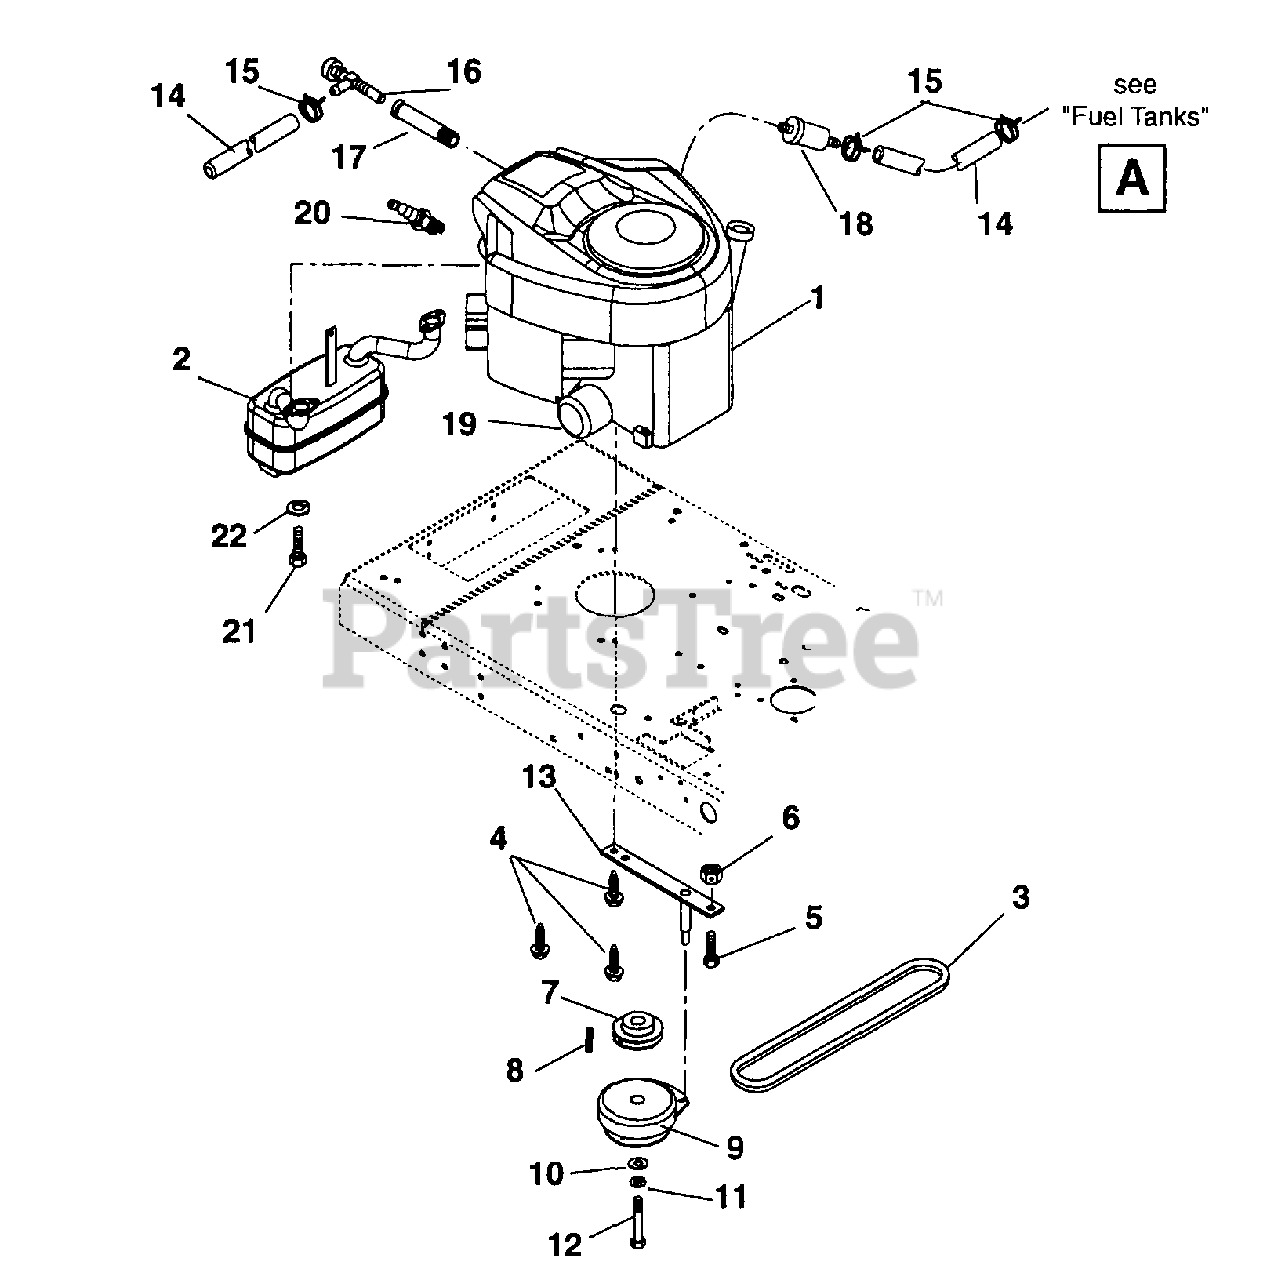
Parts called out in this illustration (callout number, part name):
1	ENGINE, 20HP B&S INTEK 6-PIN
2	MUFFLER ASSEMBLY
3	V-BELT, HA-RAW EDGE
4	@SCR-TAP .38-16X1.25 HWH TR YZ
5	@BLT-HEX .31-18X1.75 GR5 YWZC
6	@NUT-LK-CTR .31-18 YWZC
8	KEY-SQ .25X1.0X.25 SAE 8630
9	CLUTCH, ELECTRIC - WARNER
10	WSHR-FL-STL .515X1.625X.250 YZ
11	@WSHR-LK .44X.109 REG YWZC
12	BLT-HEX .44-20X3.00 GR5 YWZC
13	ANCHOR-CLUTCH
14	GAS LINE-BULK 1/4" I.D.
15	CLAMP-HOSE WIRE .490/.510X.116
16	COCK, OIL DRAIN
17	ADAPTER, OIL DRAIN
18	PLUG, SPARK - TEC. SNO-THRO
19	FILTER, OIL 20HP B&S VANGUARD
20	PLUG, SPARK 20HP B&S VANGUARD
21	SCR-SKH M8 X 1.25X20
22	@WSHR-LK .31X.078 REG YWZC
